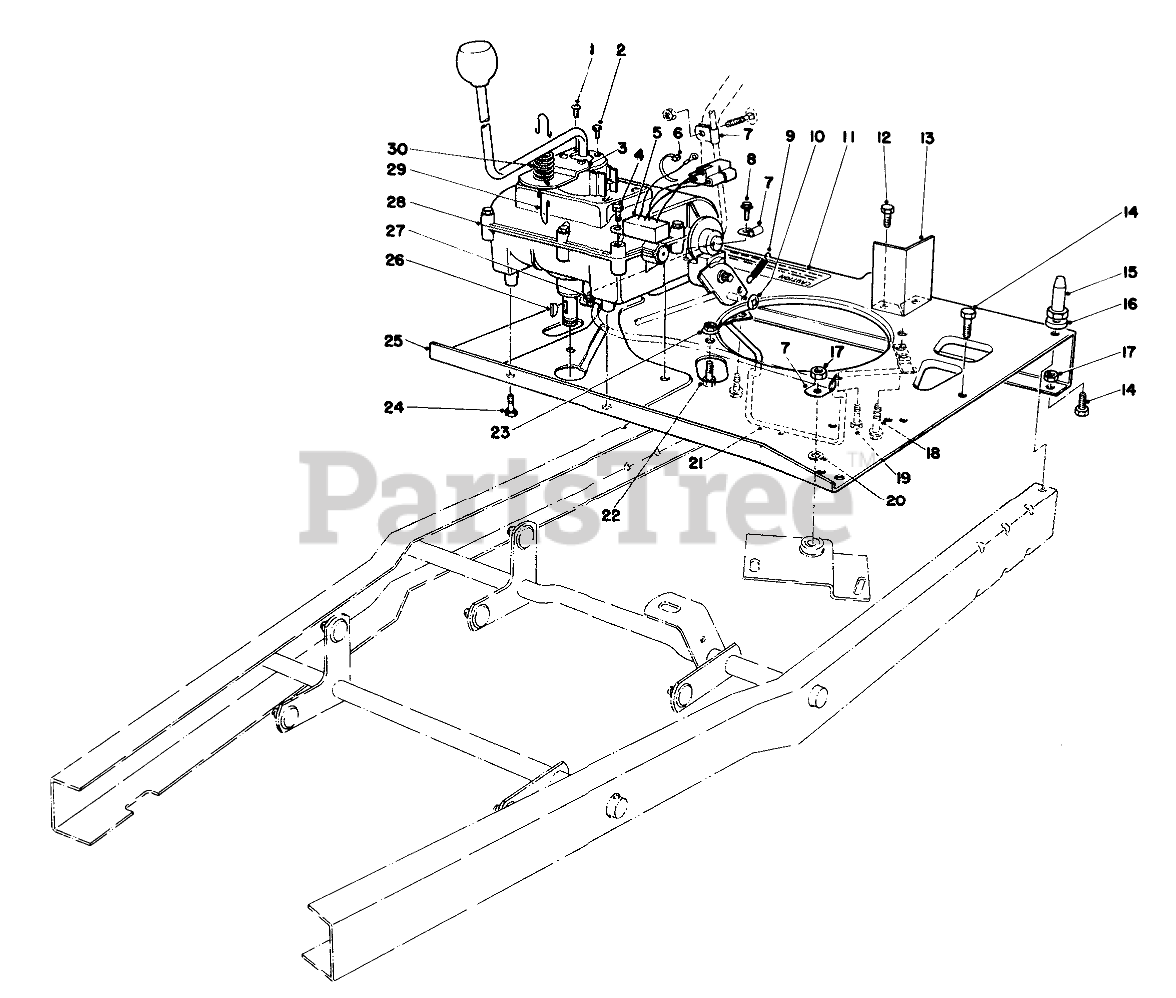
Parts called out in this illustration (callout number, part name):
3	Neutral Bracket
5	Control Module
6	TIE-CABLE
7	CLIP-FUEL LINE
8	SCREW
9	SPRING-RETURN, BRAKE
10	PUSH ON SPEED NUT 1/4
11	Decal
12	SCREW-HH
13	Baffle-Carb
14	SCREW-HH
15	PIN-MOUNTING, LOWER
16	SPACER-PIN, MOUNTING
17	NUT-LOCK, CONE
18	SCREW-HWHTF
19	Screw-HH
20	WASHER-PLAIN
21	Belt Guide
22	SCREW-HH
23	NUT-HF
24	5/16-18 X 5/8 SEMS SC
25	Plate-Engine
26	KEY-WOODRUFF
27	SCREW-HHFTF
28	Transmission
29	Neutral Spring Wire
30	SPRING
